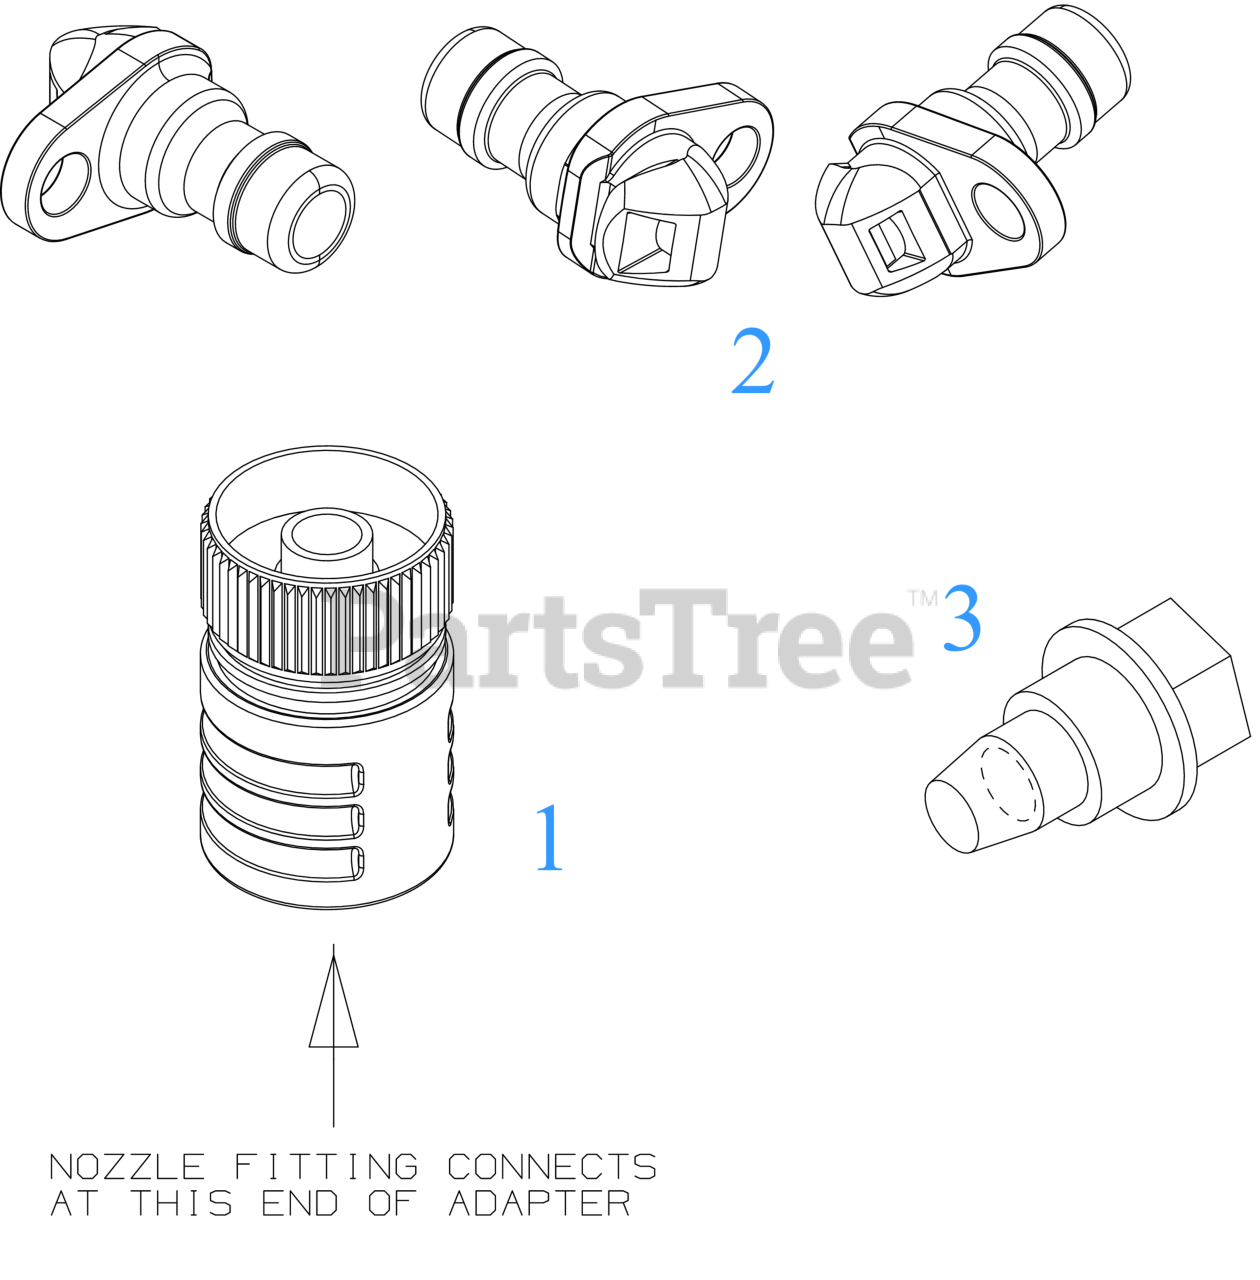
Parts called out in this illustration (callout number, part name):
1	WATER NOZZLE ADAPTER
2	DECK WASH NOZZLE
3	SHOULDER SCREW 1/4-20 x .50
